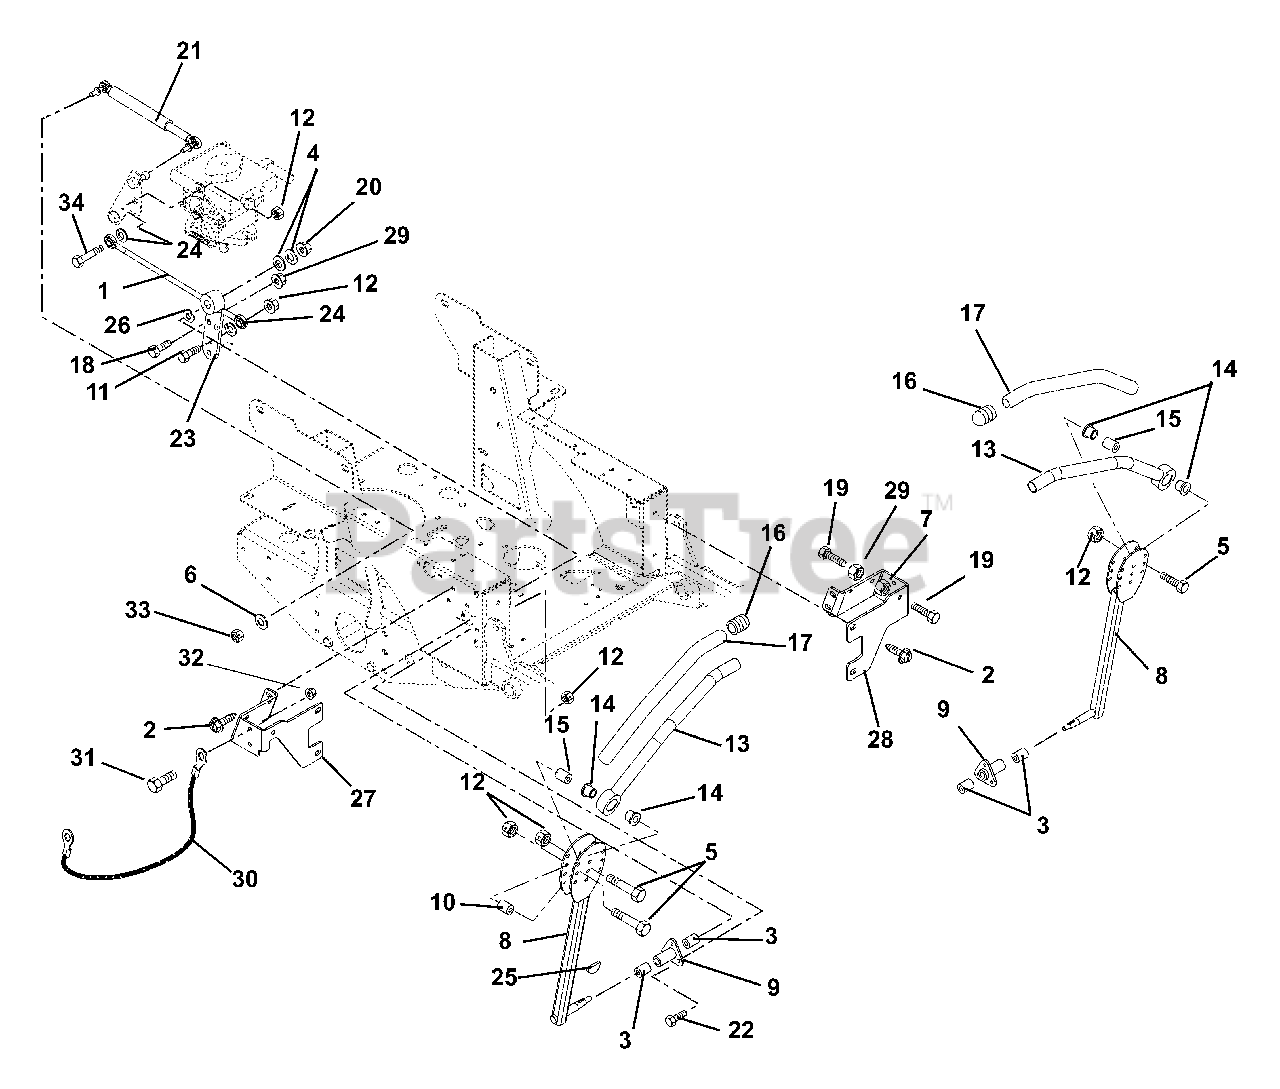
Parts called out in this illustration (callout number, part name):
1	ASSY, STEERING ROD
2	@SCR-TAP .38-16X.75 HWH TR YWZ
3	BSHG .625X.750X.500
4	@WSHR-FL-STL.406X.812X.065 YWZ
5	@BLT-HEX .31-18X1.75 GR5 YWZC
6	WSHR-FL-STL .328X1.0X.094 YWZC
7	NUT-HEX-JAM .375-16 YWZC
8	CONTROL ARM - BLACK
9	BUSHING, FLANGE
10	ECCENTRIC
11	@BLT-HEX .31-18X1.25 GR5 YWZC
12	@NUT-LK-NYL-FLG .31-18 YWZC
13	HANDLE WLDMT LH
14	BSHG-FLG .762X1.48X.44 NYL
15	SPACER .328 X .76 X 1.01
16	CAPLUG - HANDLEBAR
17	GRIP - HANDLEBAR
18	BLT-HEX .375-16X1.750 FTD YWZC
19	@BLT-HEX .38-16X1.25 GR5 YWZC
20	@NUT-LK-NYL-FLG .38-16 YWZC
21	DAMPENER
22	@BLT-HEX .31-18X1.00 GR5 YWZC
23	ARM, PIVOT
24	@WSHR-LK .31X.078 REG YWZC
25	KEY-WDRF .13X.63 HRD#5
26	WAVE WASHER .640X.875X.125FH
27	STOP, STEERING-RH (BLACK)
28	STOP, STEERING -LH (BLACK)
29	@NUT-LK-CTR-JAM .375-16 YWZC
30	CBL,HOOD
31	@BLT-HEX .25-20X.75 GR5 YWZC
32	@NUT-LK-NYL-FLG .25-20 YWZC
33	@NUT-LK-NYL M8-1.25 YWZC
34	@BLT-HEX .31-18X1.50 GR5 YWZC
